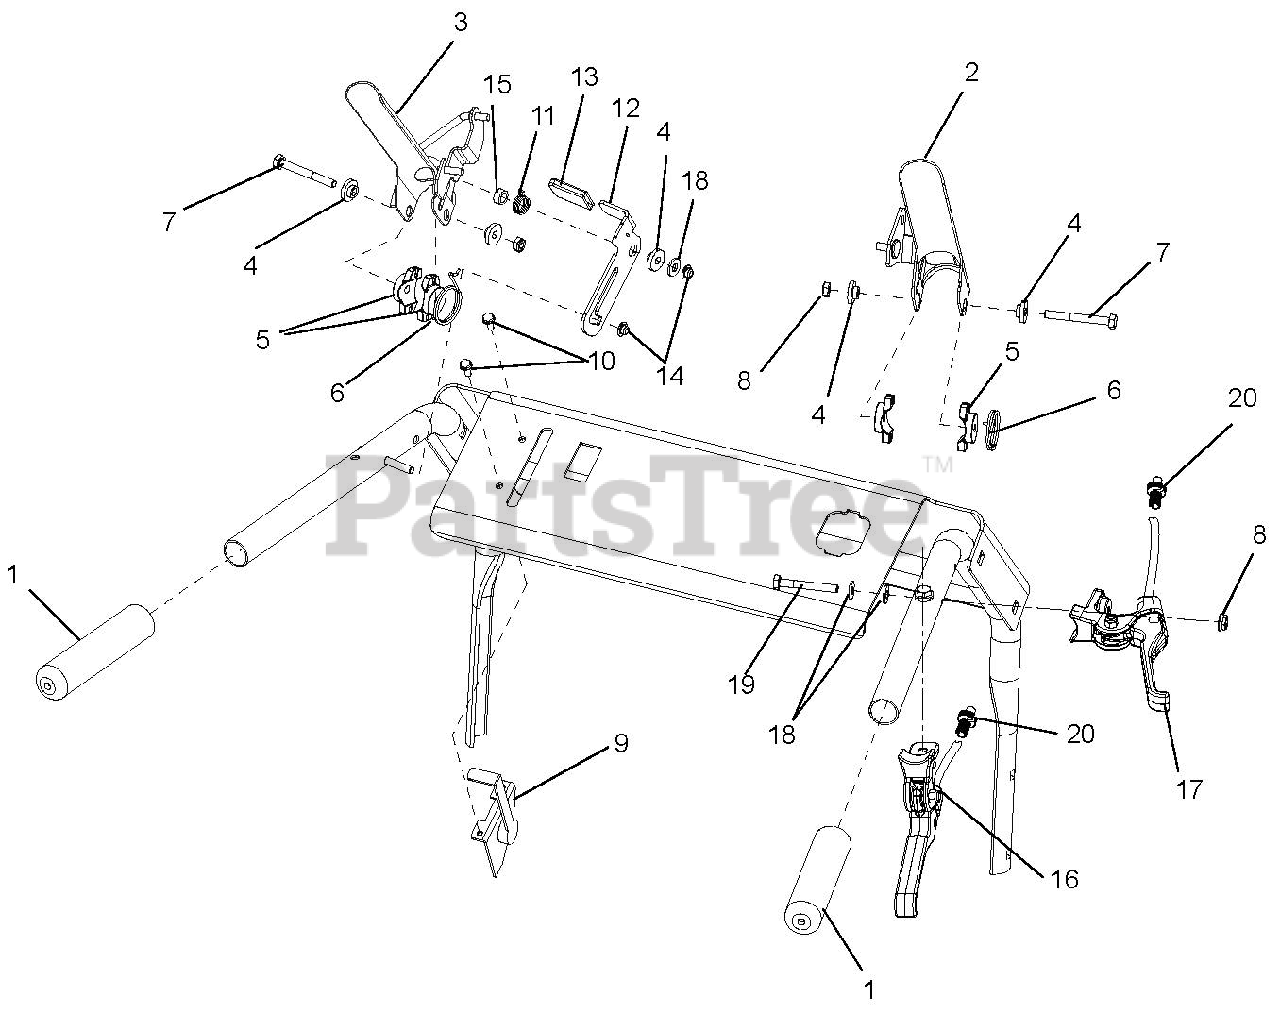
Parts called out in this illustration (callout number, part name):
1	HANDLE GRIP
2	PADDLE, WAW PARK BRAKE
3	WMT-PADDLE, WAW LH
4	BSHG, FLG .266X.42X.150 PM
5	SPACER, HANDLEBAR
6	SPRING, TORSION
7	@BLT-HEX .25-20X2.25 GR5 YWZC
8	NUT-JAM-NYL .250-20 W/INSERTYZ
9	CABLE, WAW THROTTLE
10	@SCR-TAP 10-24X.50 HWH TR YWZC
11	SG-TORS
12	BRKT-LEVER, INTERLOCK
13	GRIP, THUMB LATCH
14	PUSH NUT, .25
15	TUBE-SPACER .33X.50X.XX
16	CONTROL-LEVER W/CABLE FORWARD
17	CONTROL-LEVER W/CABLE REVERSE
18	@WSHR-FL-STL.281X.62X.065 YWZC
19	@BLT-HEX .25-20X2.00 GR5 YWZC
20	CABLE ADJUSTER, STEEL
